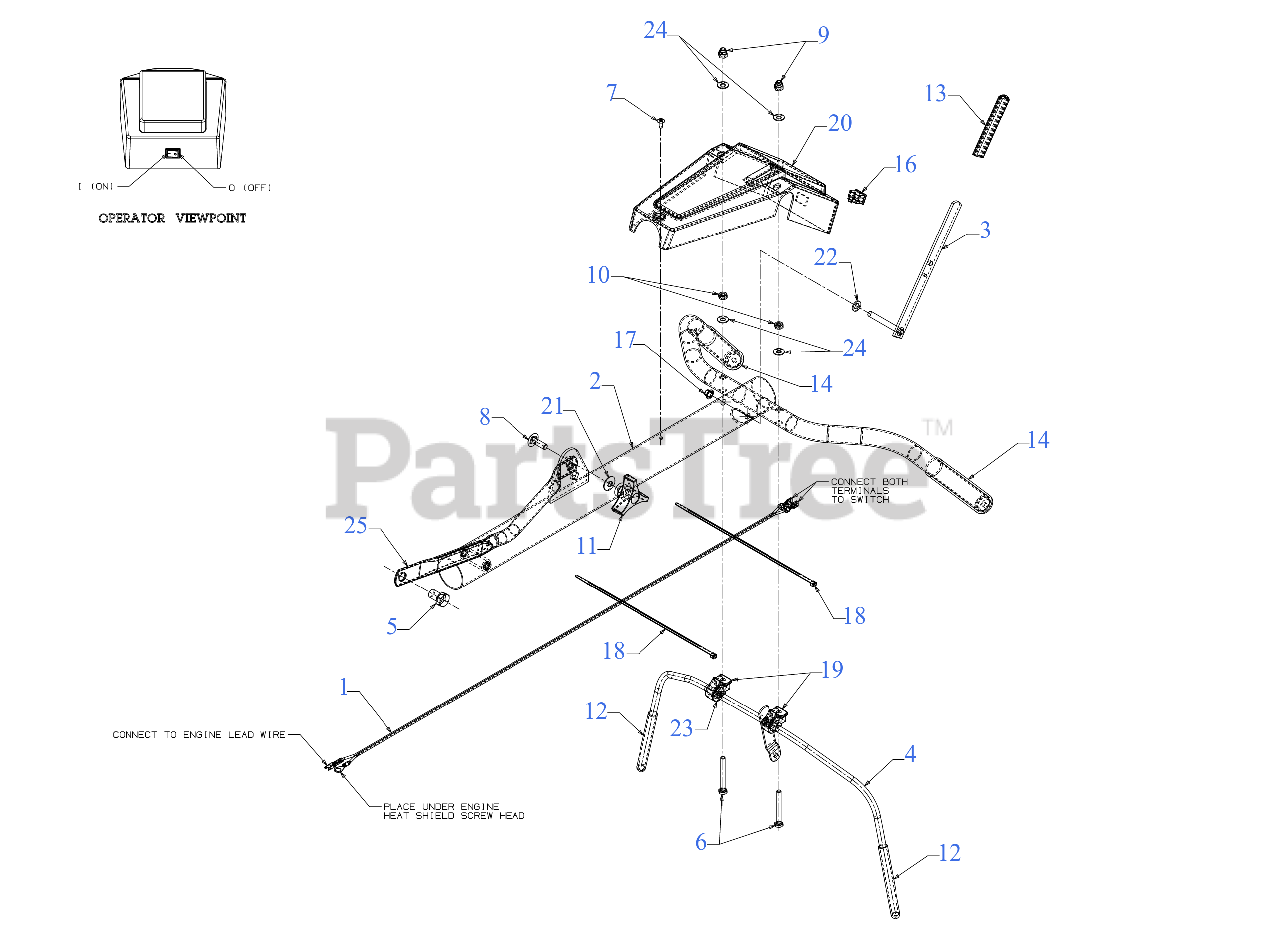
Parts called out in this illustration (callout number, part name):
1	HARNESS ASSEMBLY
2	HANDLE ASSEMBLY (MTD RED)
3	REVERSE HANDLE ASSEMBLY
4	CLUTCH HANDLE ASSEMBLY (POWDER BLACK)
5	BOLT 1/2-20 x .75 GR5
6	SCREW 1/4-20 x 2.25 GR5
7	SCREW #10-16 x .500
8	SCREW 5/16-18 x 1.00
9	HEX NUT ACORN
10	HEX NUT
11	HANDLE KNOB
12	CLUTCH GRIP
13	REVERSE LEVER GRIP
16	POSITIVE SWITCH- ON/OFF
17	SPEED NUT
18	CABLE TIE
19	CLUTCH HANDLE HOLDER
20	HANDLE COVER
21	BELL WASHER .337 X.867 x .057
22	FLAT WASHER .344 x .62
23	FLAT WASHER.40 ID
24	FLAT WASHER .266X.625
